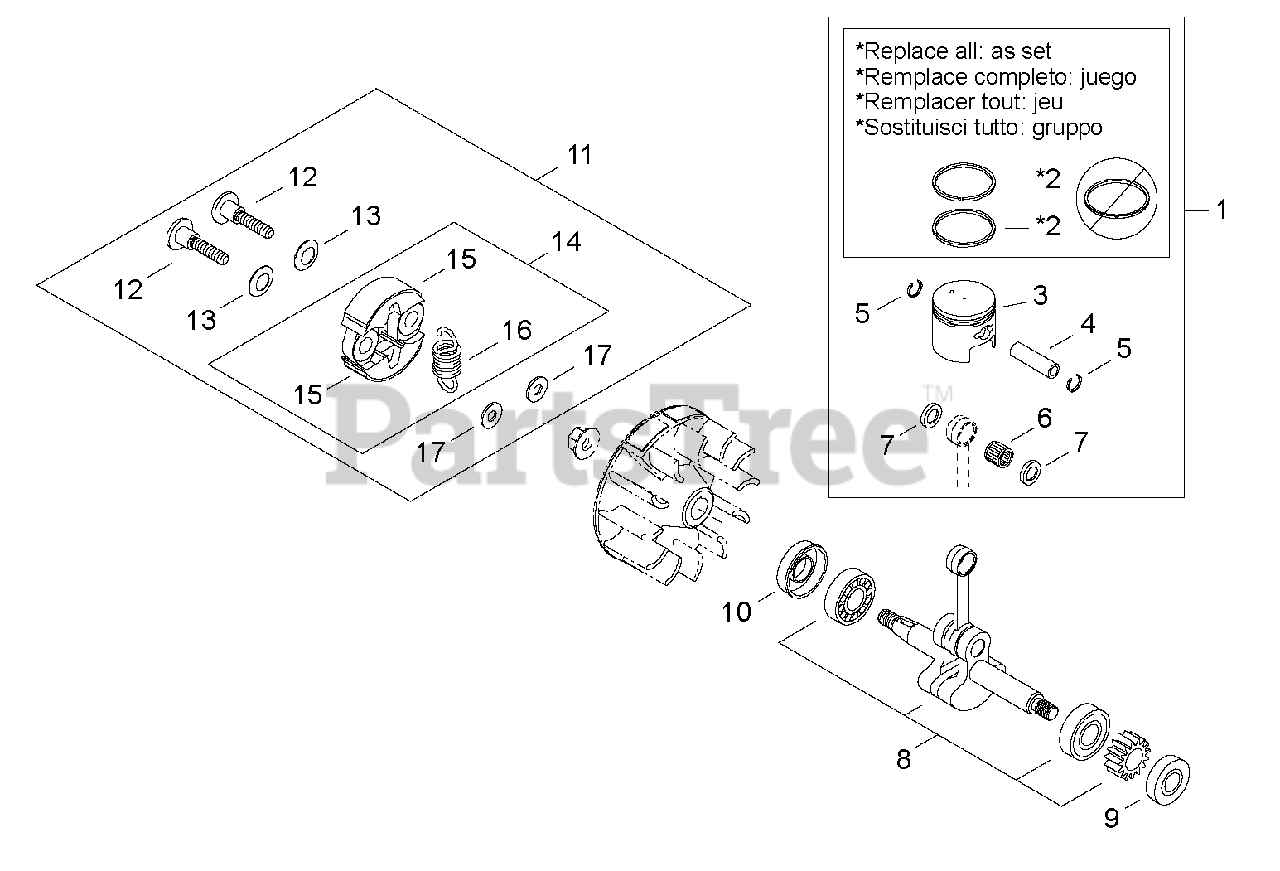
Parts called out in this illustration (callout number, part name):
1	PISTON KIT
2	RING, PISTON
3	PISTON
4	PIN, PISTON
5	RING, RETAINING
6	BEARING, NEEDLE
7	SPACER, PISTON
8	CRANKSHAFT ASSY
9	SEAL, OIL - 12
10	SEAL, OIL - 12
11	CLUTCH SHOE SET
12	BOLT, CLUTCH
13	WASHER - SPRING
14	CLUTCH ASSY
15	SHOE, CLUTCH
16	SPRING, CLUTCH
17	WASHER - 6
